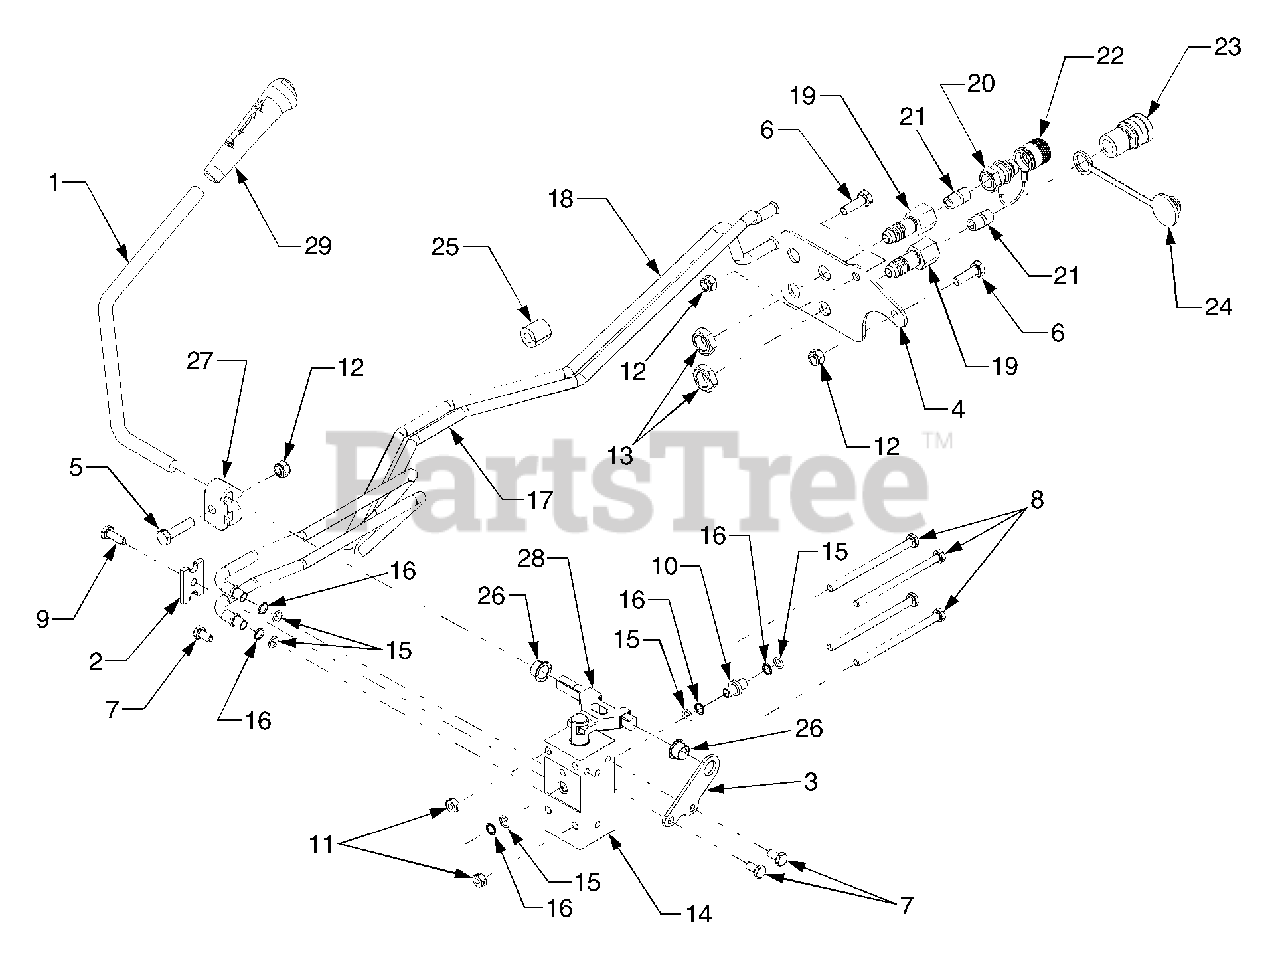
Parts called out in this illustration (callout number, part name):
1	Handle Ass'y.
2	Clamp, Double Valve
3	Bracket, Lift Valve
4	Bulkhead, Fitting
5	Screw, Hex Cap, 5/16-18 x 1.25 GR5
6	Screw, Hex Cap, 5/16-18 x .625 GR5
7	Screw, Hex Cap, 1/4-20 x .5 GR5
8	Screw, Hex Cap, 1/4-20 x 4.0 GR2
9	Screw, Hex Cap, 1/4-20 x .75 GR5
10	Fitting, Union
11	Nut, Hex Lock, 1/4-20 GRA
12	Nut, Hex Nylon Insert Lock, 5/16-18 GR5
13	Nut, Hex Jam, 9/16-18 GR5
14	Valve, Hydro
15	O-Ring
17	Tube, Hydraulic (Up)
18	Tube, Hydraulic (Down)
19	Fitting, Bulkhead
20	Coulpling, Male
21	Fitting, Pipe Nipple
22	Cap, Protective Coupling
23	Coupling, Female
24	Cap, Protective Coupling
25	Pad, Bumper
26	Bearing, Nylon Flange
27	Clamp, Handle
28	Link, Lift
29	Grip, Handle
